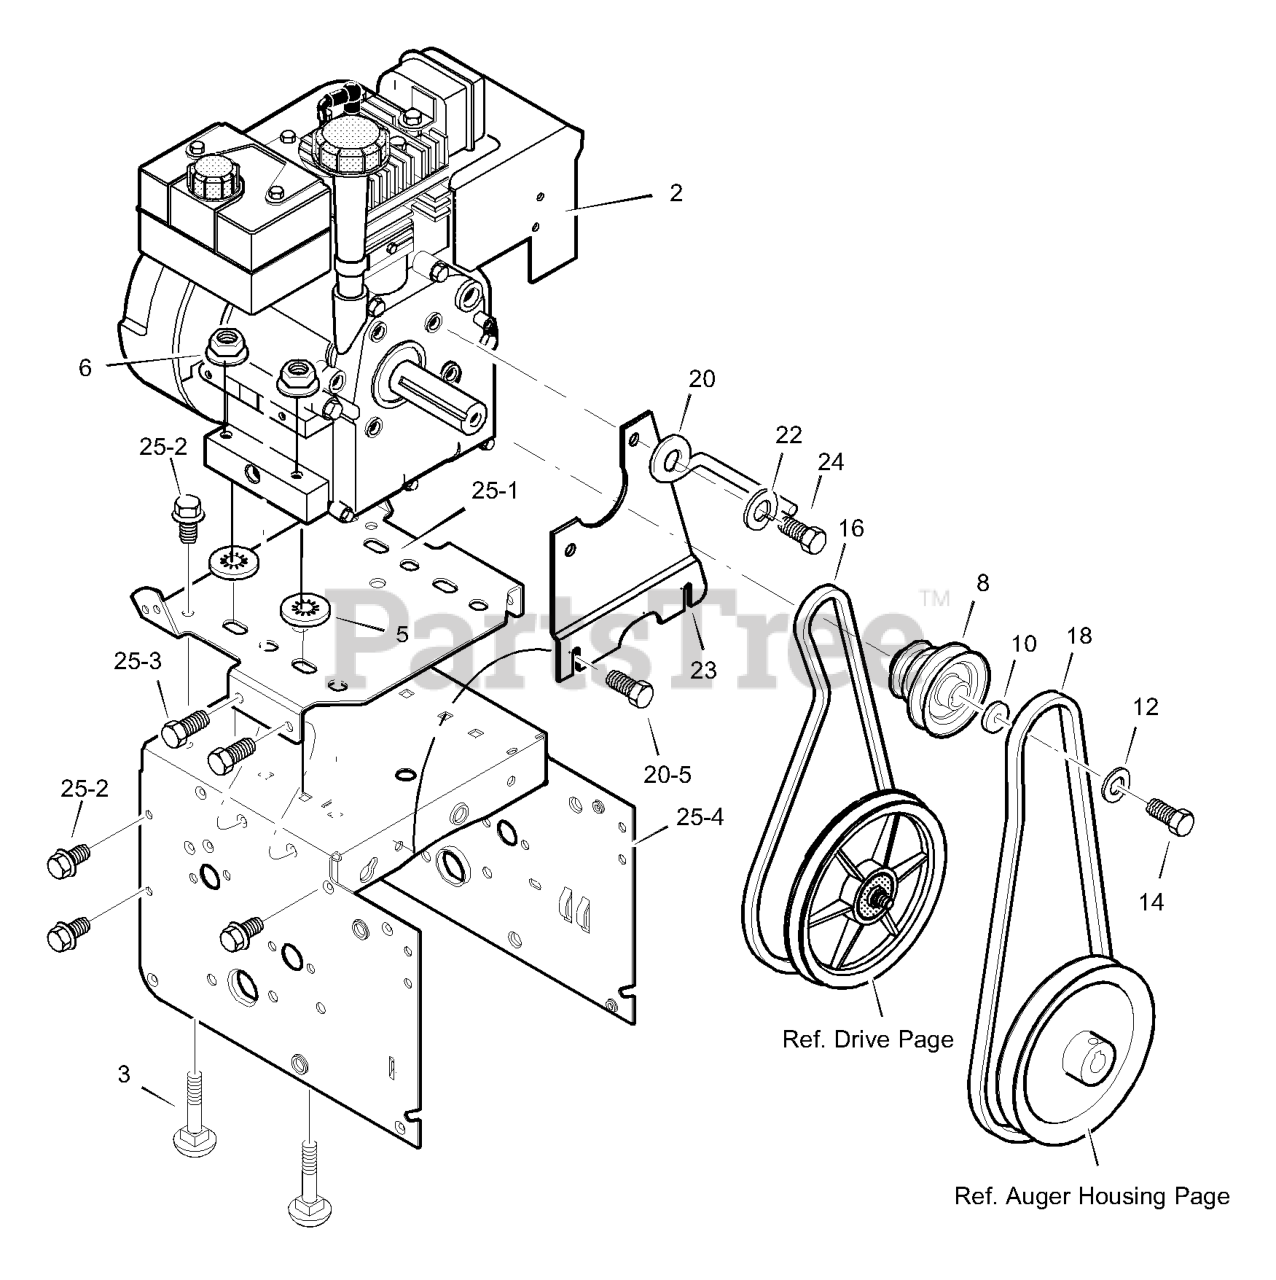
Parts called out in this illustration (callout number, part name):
2	ENGINE
3	BOLT, CARRIAGE 5/16-18
5	RETAINER, PUSH
6	NUT, HEX 5/16-18
8	PULLEY, ENGINE
10	WASHER
12	WASHER .38ID
14	SCREW, 3/8-24 x 1.00
16	BELT, V 3L 33.13LG
18	BELT, V 4L 38.1MF16" 5-10
20	GUIDE, BELT
22	WASHER, SPTLK .31X.58X.08
23	PLATE, ANTI VIBRATION
24	SCREW, 5/16-24 x 1.00
25	FRAME ASSEMBLY
25-1	PLATE, ENGINE MOUNT
25-2	SCREW, TAP 1/4-20 X .63
25-3	SCREW, TAP 5/16-18 X .50
25-4	FRAME, MOTOR BOX
